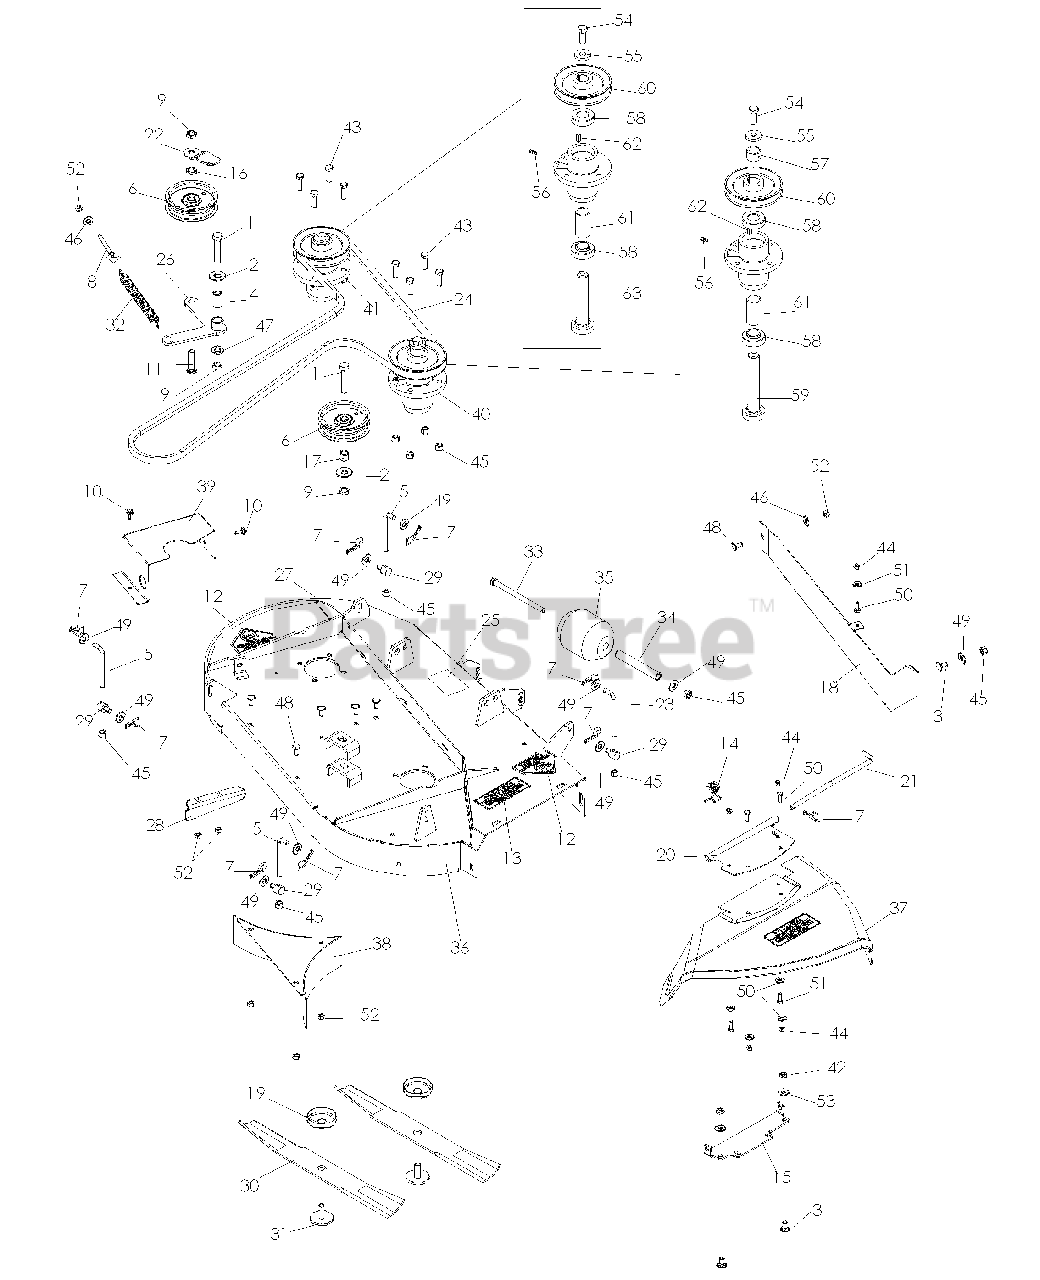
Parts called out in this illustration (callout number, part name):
1	HEX SCREW 1/2-13 X 2.5" GR 5
2	WASH USS FLAT 1/2
3	RHSNB 3/8-16 X 3/4 GR5 ZD
4	BUSHING DIXON 1080
5	L ROD 3-7/8
6	PULLEY IDLER
7	PIN, COTTER 1 3/4
8	EYE BOLT 5/16 X 3.50
9	NUT, 1/2-13 THIN PROF NYL
10	SCREW, TAP & DR #12-14 X 3/4
11	STUD 1/2-13 X 2
12	DECAL, CPSC
13	DECAL, DANGER
14	SPRING, TORSION
16	HD PULLEY SPACER
17	BUSHING
19	TRASH GUARD
20	MT. BRACKET W/DECAL
21	DEFLECTOR PIN
22	BELT GUARD BLK
23	L-ROD 4.25
25	DECAL, BELT ROUTING
26	IDLER ARM WLDT., BLACK
27	DECAL, DECK 36"
28	BAFFLE DECK
30	BLD 36" HI LIFT FUS
31	BLADE BOLT
32	SPRING, DECK BELT
33	BOLT 3/8 X 6 GR5
34	BUSHING
35	ROLLER 3-3/4 DIA. X 4-1
36	DECK W/V-BAFFLE 36" DIX
37	PLASTIC DEFLECTOR 36
38	BAFFLE WLDT
39	PULLEY GUARD
40	HUB ASM RH
41	HUB ASM LH
42	NUT HEX 3/8-16 NYLON, THIN
43	HCS 3/8C X 1 1/4 GR5
44	NUT 1/4-20 NYLOC
45	NUT 3/8-16 NYLOC
46	FLAT WASHER 5/16 SAE
47	WASHER 1/2" FLAT
48	BOLT 5/16C X 3/4" CARRIAGE
49	WASHER 3/8 FLAT
50	HCS 1/4C X 3/4 HCS
51	WASHER 1/4 FLAT
52	NUT 5/16 NYLOC
53	WASHER 5/16 FLAT
54	1/2-20 UNF X 1 1/4 HHBLT
55	WASHER .525 X 1.375 X .25
56	ZERK, 3/16, DRIVE IN
57	SPACER HUB
58	BEARING-ECC LOCK
60	PULLEY 5``B`
62	OUTER SHAFT KEY
63	SHAFT 50S
